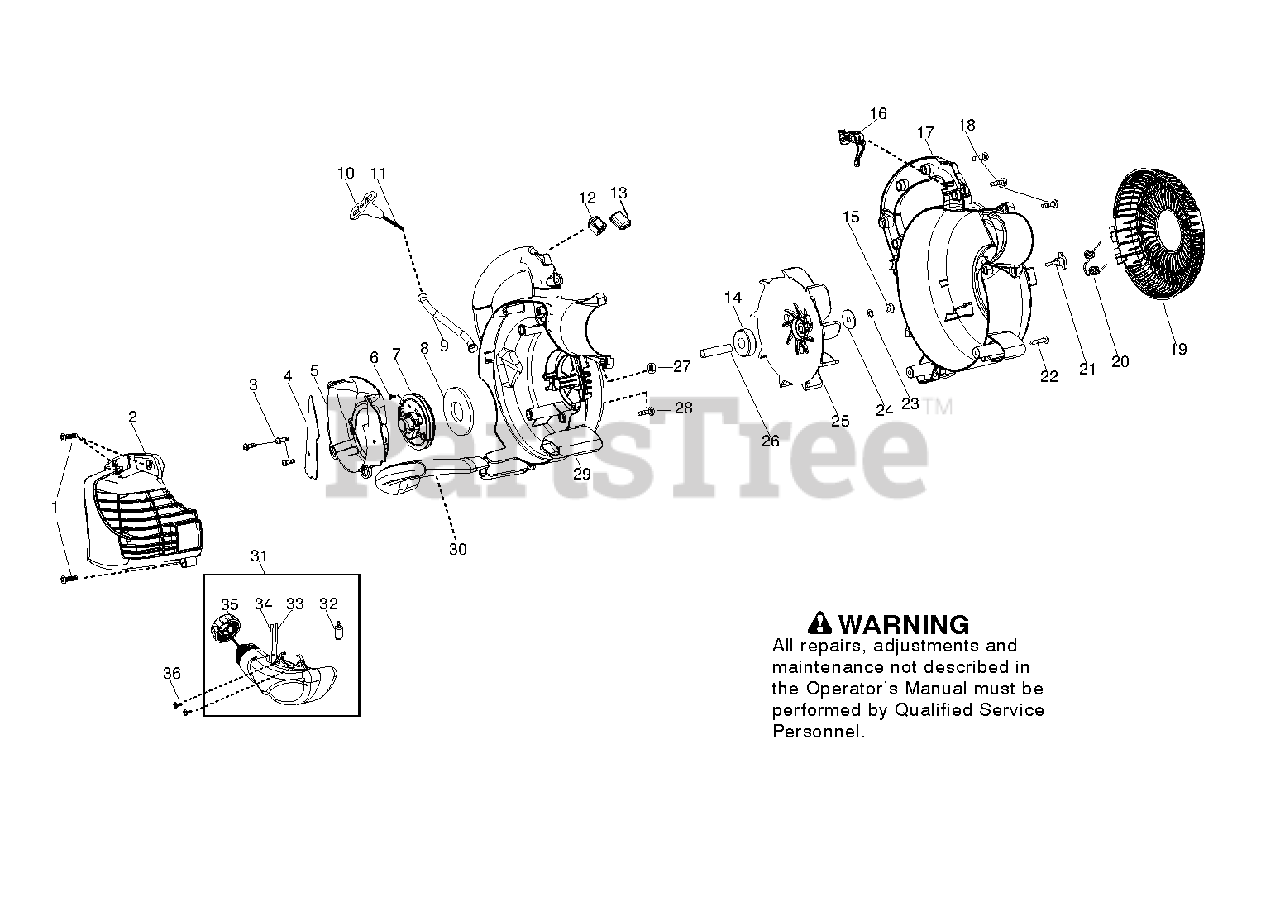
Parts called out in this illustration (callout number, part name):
2	ASSY COVER ENGINE
4	SHIELD BAFFLE
6	SCREW SEMS TOOTHED WASHER
7	KIT STARTER PULLEY
8	KIT STARTER SPRING
9	TUBE STARTER ROPE
10	HANDLE STARTER BLK
11	KIT ROPE
12	KIT SWITCH
13	Protector Switch
14	Hub Bearing
16	TRIGGER THROTTLE RED
17	COVER
19	DOOR VAC BLACK
20	SPRING VAC DOOR
21	KNOB BLOWER
22	SCREW #10 PLASTITE 1.362
23	LOCK WASHER
24	Impeller Washer
25	ASSY IMPELLAR HUB
26	SPACER FLYWHEEL
29	ASSY SCROLL RIGHT
30	HANDLE VAC BLACK
31	FUEL TANK
32	FUEL PICK-UP ASSY
33	KIT-LINE
34	LINE KIT
35	ASSY FUEL CAP W/RETAINER
36	SCREW FUEL TANK RETAINER
